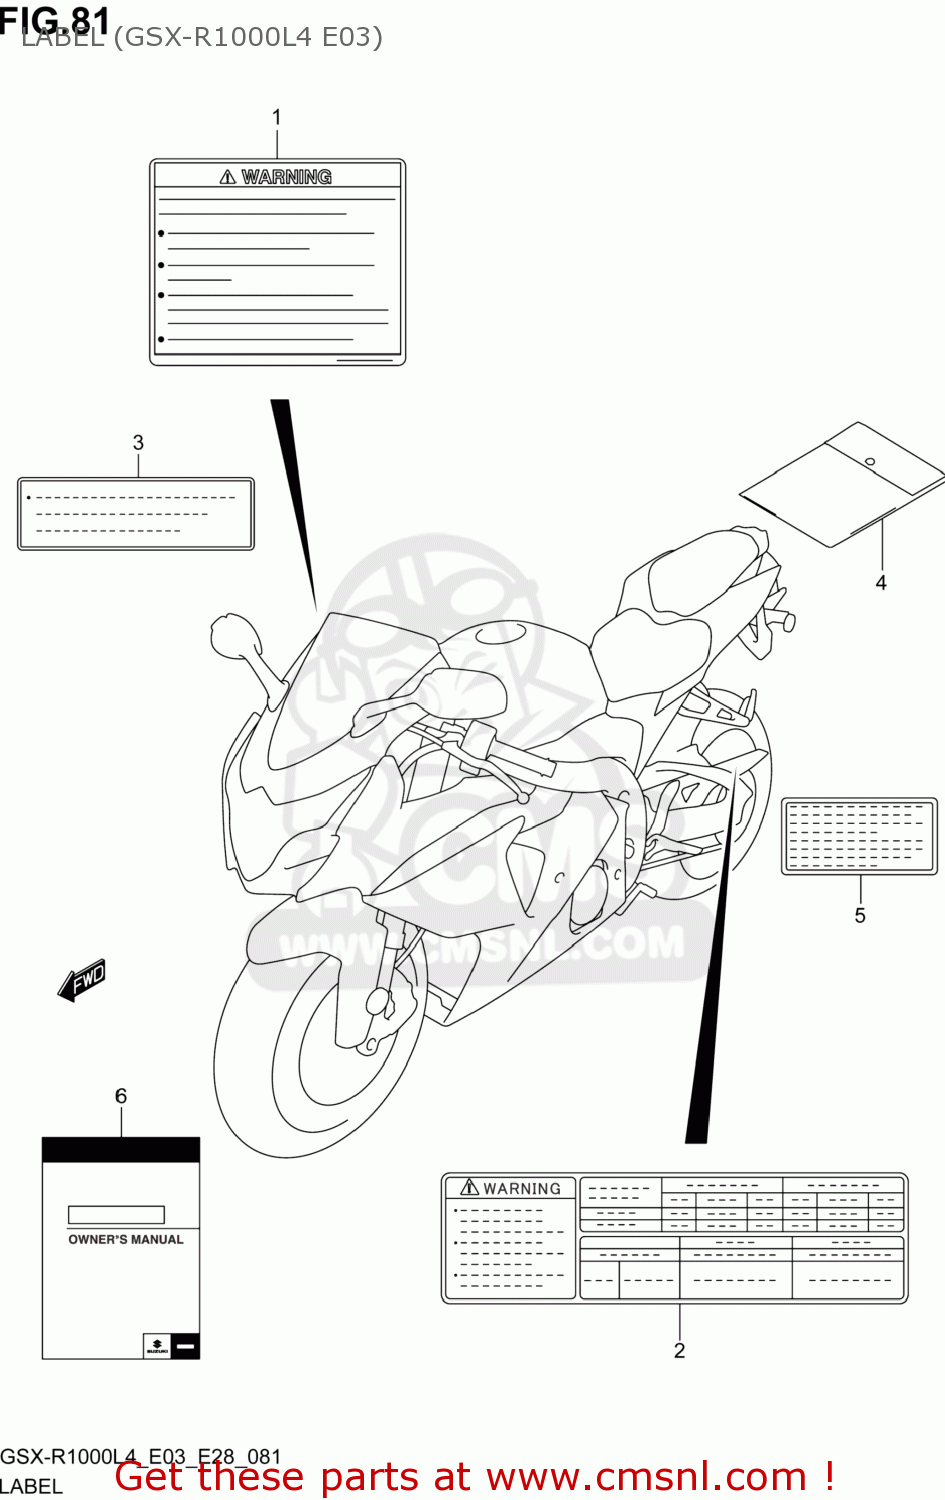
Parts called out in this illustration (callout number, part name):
1	LABEL,GENERAL WARNING
2	LABEL,TIRE INFORMATION
3	LABEL,FUEL INFORMATION
4	BAG,OWNER'S MANUAL
5	LABEL,MANUAL NOTICE
6	MANUAL,OWNER'S
